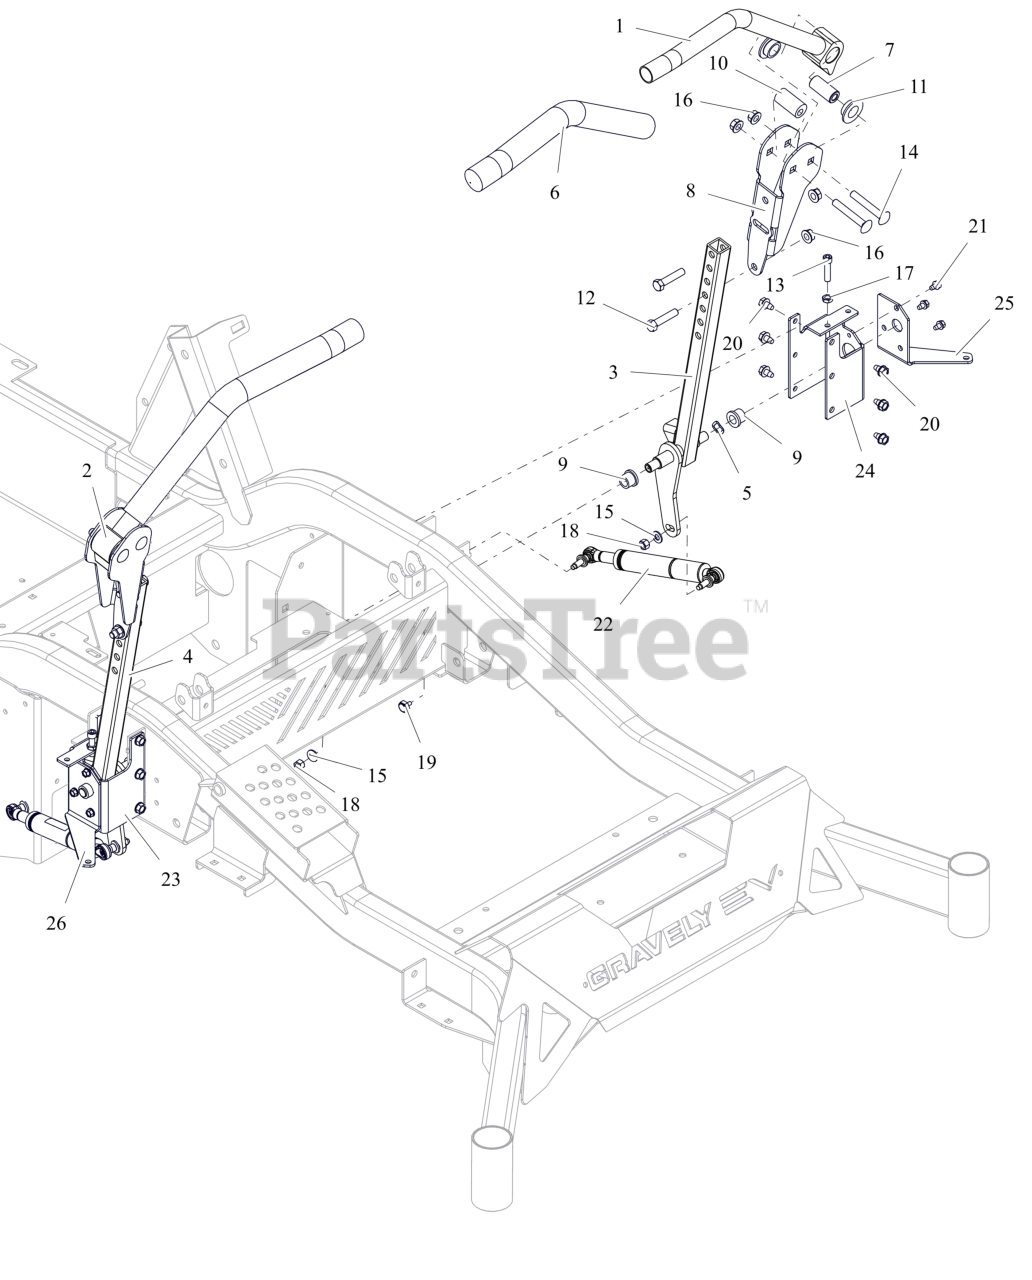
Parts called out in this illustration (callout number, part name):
1	WLDMT, CONTROL HANDLE-LH (RED)
2	WLDMT, CONTROL HANDLE-RH (RED)
3	WLDMT, STEERING -LH (RED)
4	WLDMT, STEERING RH (RED)
5	WAVE WASHER .531X.781X.125FH
6	GRIP, HANDLEBAR
7	SPACER, STEERING ARM
8	BRKT, ADJ UPPER CONTROL ARM (RED)
9	BSHG, FLG .516X.750X.625X.937
10	BSHG, ECCENTRIC.406X.875X1.625
11	BSHG-FLG .762X1.48X.44 NYL
12	BLT, HEX .38-16X1.75 G5 ZCC
13	SCR, SKH .312-18X1.25 GR8 ZC120
14	BLT, RHSSN.38-16X2.50 G5 ZCC
15	WSHR, HRDN 0.344X0.688X0.065
16	NUT-LK-TOP-FLG .38-16 ZC120
17	NUT-JAM .312-18 G2 ZCC
18	NUT-LK-TOP-FLG M8 ZCC
19	BOLT, MAGNETIC STEERING SENSOR
20	SCR,TAP .312-18X.50 HWH TR ZCC
21	SCR,TAP .25-20X.375 HWH TR ZCC
22	DAMPER, NEUTRALIZING
23	BRKT, STEERING ARM MOUNTING-RH (RED)
24	BRKT, STEERING MOUNTING -LH (RED)
25	BRKT, FRONT FENDER MOUNT-LH (BLACK)
26	BRKT, FRONT FENDER MOUNT-RH (BLACK)
